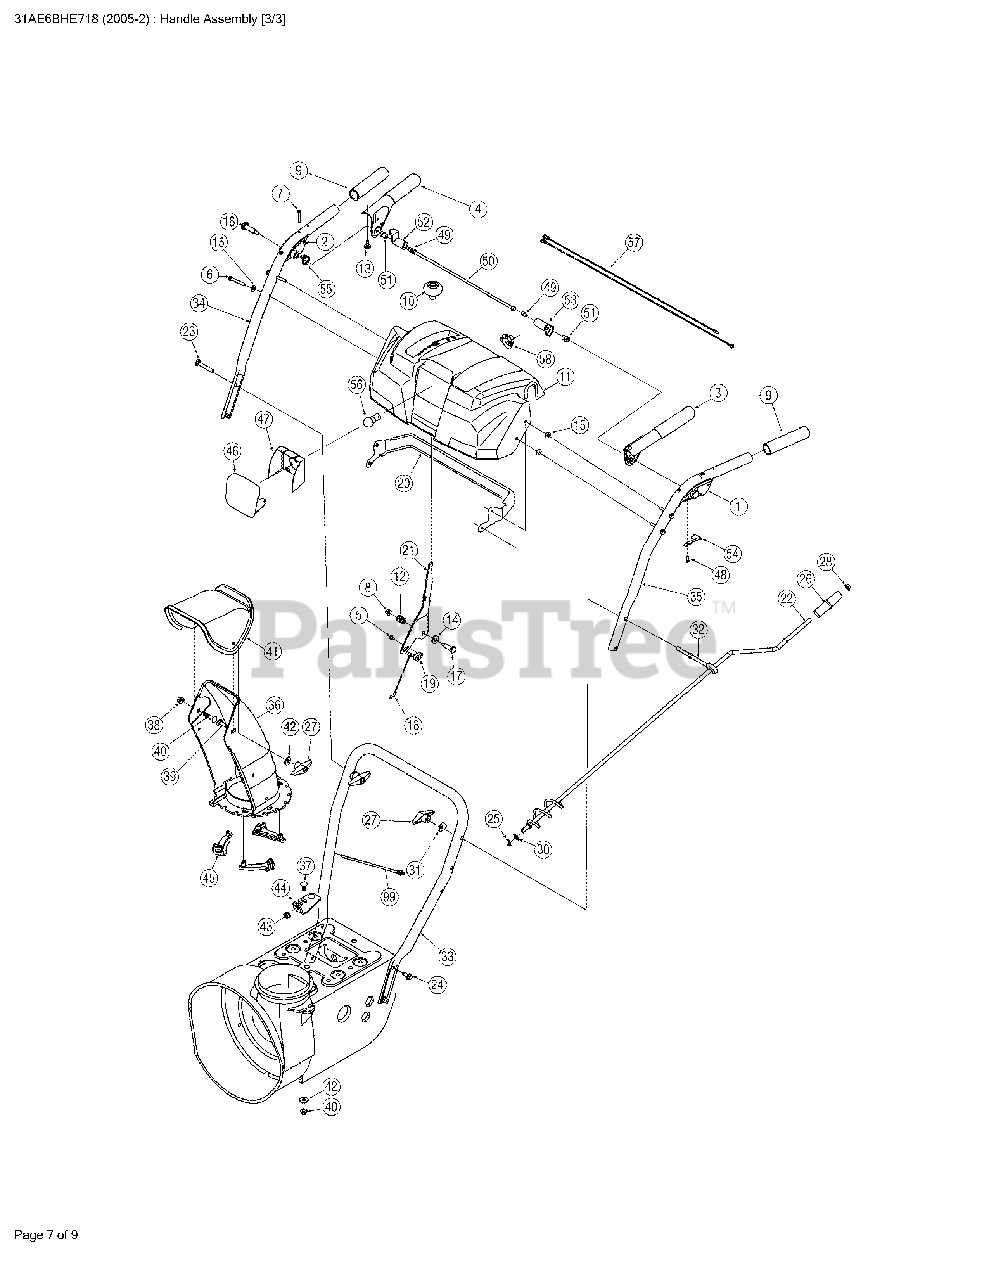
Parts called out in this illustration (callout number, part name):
1	Handle Assembly, Lock, LH
2	Handle Assembly, Lock, RH
3	Handle Ass’ y, Engagement LH
4	Handle Ass’y, Engagement, RH
5	Screw, #10-16, 0.500
6	Screw, 1/4-20, 1.750
7	Screw, Machine, #10-24, 1.375
8	Nut, Flange Lock, 1/4-20,
9	Grip, 1.0 ID x 5.0
10	Knob, Shift
11	Handle Panel, H-Style, Black
12	Spring, .39 x .60 x .88
13	Bumper, Rubber, .62 OD x .22
14	Washer, Flat, .385 x .870 x .092
15	Washer, Flat, .25 x .630 x .0515
16	Screw, Shoulder, .43 x 1.34, 1/4-20
17	Screw, Shoulder, .374 Dia. x 1.05
18	Cable, Speed Selector
19	Barrel Holder, Cable, LH
20	Bracket, Panel
21	Lever, Shift
22	Crank Assembly, Chute
23	Screw, Carriage, 5/16-18, 2.25
24	Screw, 5/16-18, 0.75, Gr5
25	Pin, Cotter, .072 x 1.13
26	Crank Knob, 1.0 Dia. x 3.2, Black
27	Knob Assembly, Wing Nut, 5/16-18
28	Cap, Push, 3/8 Rod
29	Grommet, .44 ID x .94 OD x .50
30	Washer, Flat, .375 x .738 x
31	Washer, Saddle, 320 x .93
32	Eye Bolt, Chute Crank
36	Chute, Lower, 5.0 Diameter
37	Bolt, Carriage, 5/16-18, 1.0
38	Nut, Flange Lock, 5/16-18, Nylon
39	Bolt, Carriage, 5/16-18, 1.0
40	Bolt, Carriage, 5/16-18, .750
41	Chute, Upper, w/ Label
42	Washer.349 ID x .879 OD
43	Bushing, Plastic, .380
44	Bracket, Chute Crank
45	Flange Keeper, Chute
47	Reflector Label, Lens
48	Screw, #8-16 x 0.50
49	Screw, 1/4-20 x.375
50	Pivot Rod
51	Shoulder Nut, 1/4-20
52	Lock Plate
53	Clutch Lock Cam
54	Clutch Lock Spring
55	Torsion Spring
57	Wire Harness, Lamp
58	Light Socket
